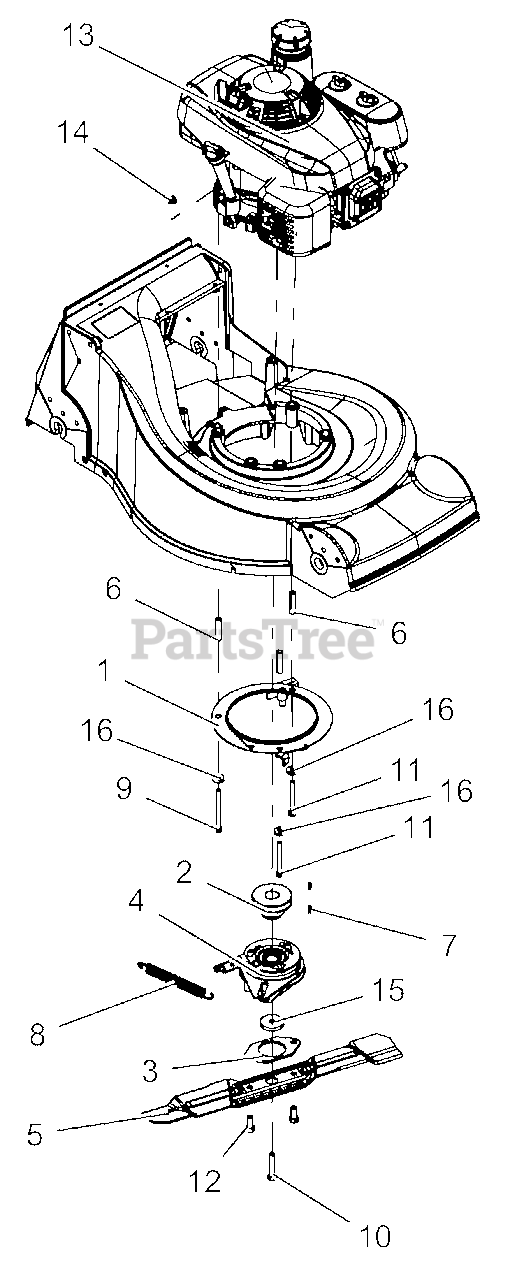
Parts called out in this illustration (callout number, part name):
1	WLDMT, PLATE -BBC
2	PULLEY, GROUND DRIVE-WLDMT
3	SPCR, BBC BLADE
4	HONDA, BBC
5	BLADE, MOWER 21" HIGH-LIFT
6	BSHG, SLV .322 X .438 X 1.824
7	KEY-WDRF .156X.625X.25 SAE 6
8	SPRG, EXTENSION BBC
9	BLT-HEX .31-18X3.50 GR5 YWZC
10	BLT-HEX .38-24X2.00 YWZC GR8
11	BLT-HEX .31-24X2.75 GR5 YWZC
12	BLT-HEX M10 X 1.5X20 GR5 YWZC
13	ENGINE, HONDA BBC-CARB
14	NUT, LK-TOP-FLG .312-18 YWZC
15	WSHR-FL-STL .400X1.75X.250
16	WSHR-FL-STL .328X.87X.179 YWZC
